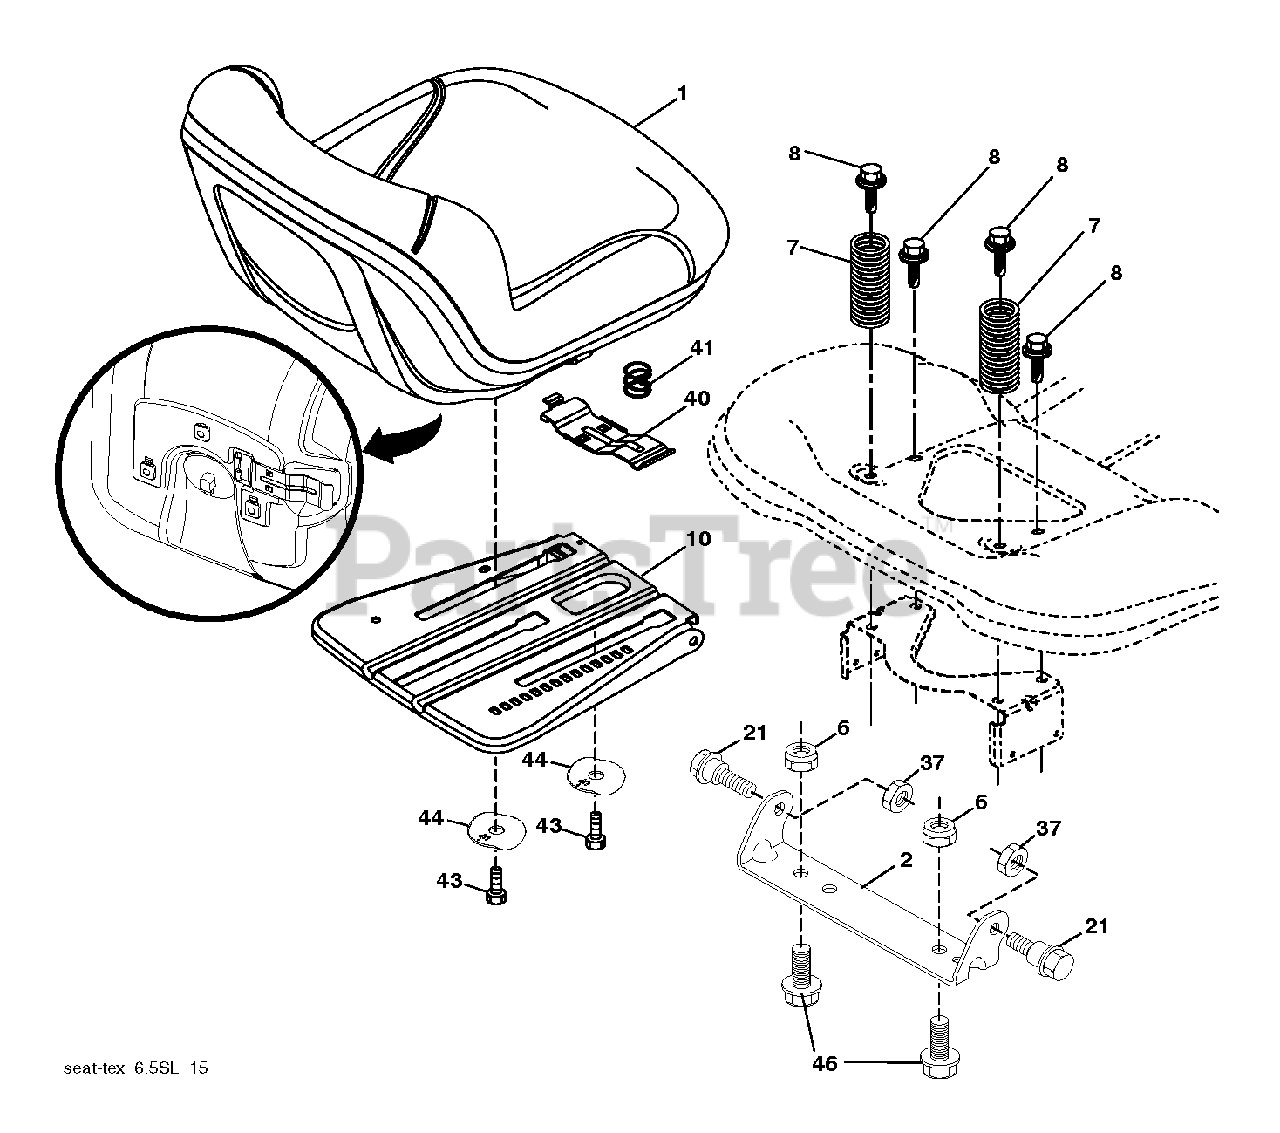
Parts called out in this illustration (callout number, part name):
1	SEAT.TH150.MS498.GRY.HUSQ.TEX
2	BRKT.PIVOT.FENDER
6	NUT
7	SPRING.COMPRESS.SEAT.
8	BOLT, 5/16-18 X 1 3/4
10	Seat Slide Plate, Pnt
21	BOLT.5/16-18X5/8.SHOULDER
37	NUT.71038.31-18.HEX.NYLOCK
40	HANDLE.SLIDE.SEAT.TEX.BLACK
41	SPRING.LATCH.SEAT.TEX
44	Winged Washer, 38Id 1
46	BOLT.3/8-16X1;1.25OD.WSHR.SEMS
